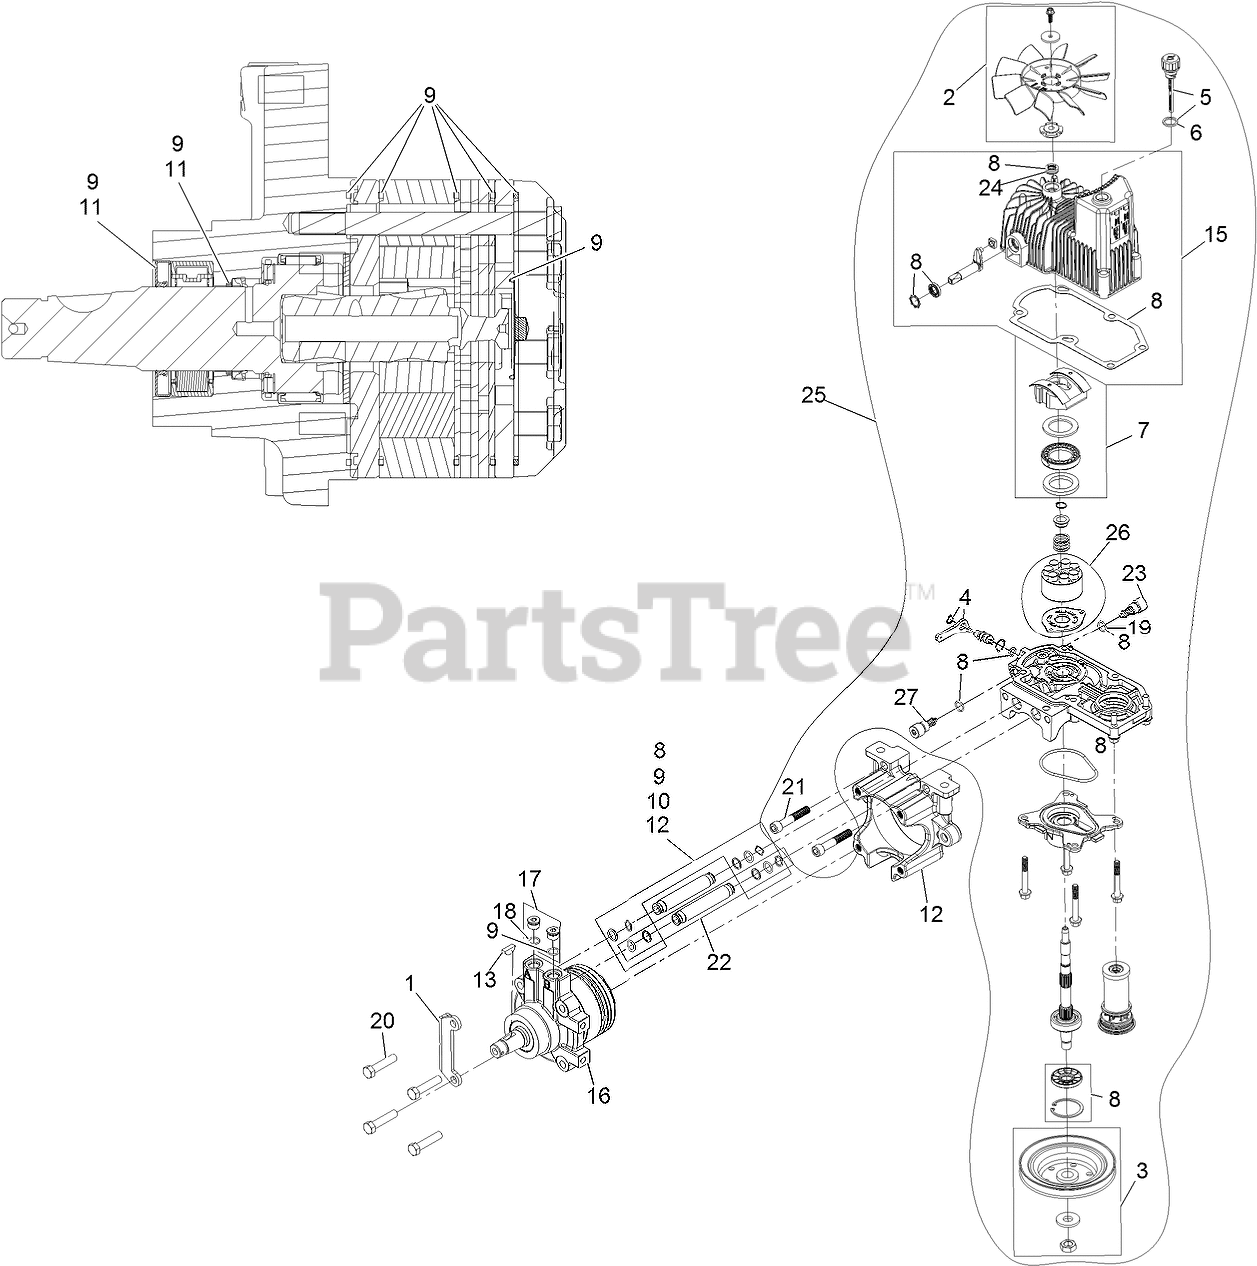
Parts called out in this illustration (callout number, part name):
1	Plate, Horse Shoe Mount
2	Kit, 7.8 In Fan
3	PULLEY KIT
4	HANDLE-BYPASS VALVE, HYDRO
5	DIPSTICK-HYDRO W/GASKET
6	GASKET-DIPSTICK, HYDRO
7	SWASH BLOCK KIT
8	Kit, Pump Seal
9	MOTOR SEAL KIT
10	TUBE SEAL KIT
11	OUTPUT SHAFT SEAL KIT
12	NOSE CUP-UHT
13	KEY-WOODRUFF
15	Kit, Housing-Hydro LH
16	KIT, MOTOR TG310CC LH
17	MAGNETIC PLUGS SERVICE KIT
19	O-RING-CHECK VALVE
20	SCREW HH
21	SCREW-HSH
22	HYDRAULIC TUBE KIT
23	SHOCK VALVE, 12CC HYDRO
24	SEAL-FAN DRIVE
25	Kit, Pump Section 16Cc LH
26	Kit - 16Cc Port Plate,Rotate Grp
27	Shock Valve Orificed 3800
